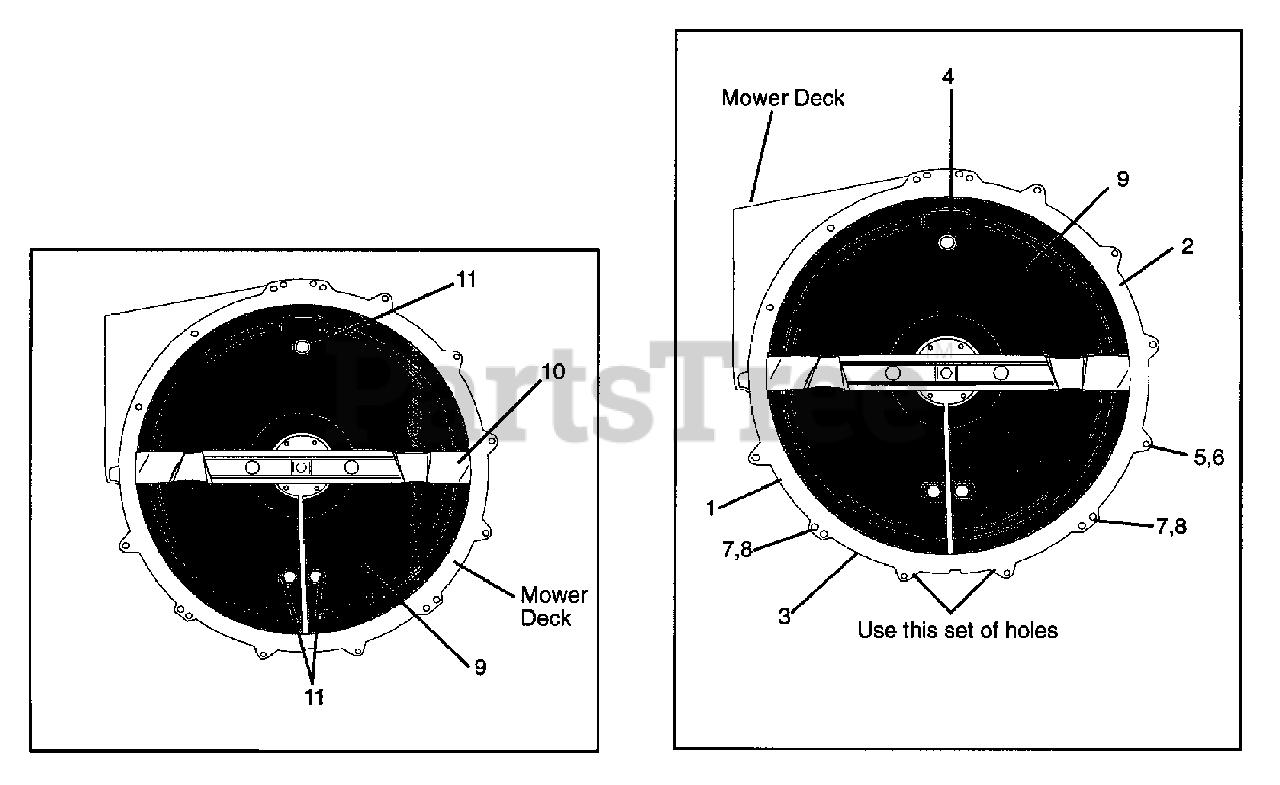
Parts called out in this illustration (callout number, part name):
1	30 IN FLANGE R H
2	30 IN FLANGE L H
3	BACK FLANGE
4	FRONT CLAMP
5	@BLT-RDHDSQNK .25-20X.75 G5YZ
6	@NUT-LK-CTR .25-20 YWZC
7	@NUT-LK-CTR .31-18 YWZC
8	@NUT-LK-CTR .31-18 YWZC
9	30" MULCHMASTER DOME INSERT
10	30" MULCHING BLADE
10	30" MULCHMASTER DOME MULCH KIT
11	@SCR-TAP .31-18X.75 HWH TR YWZ
